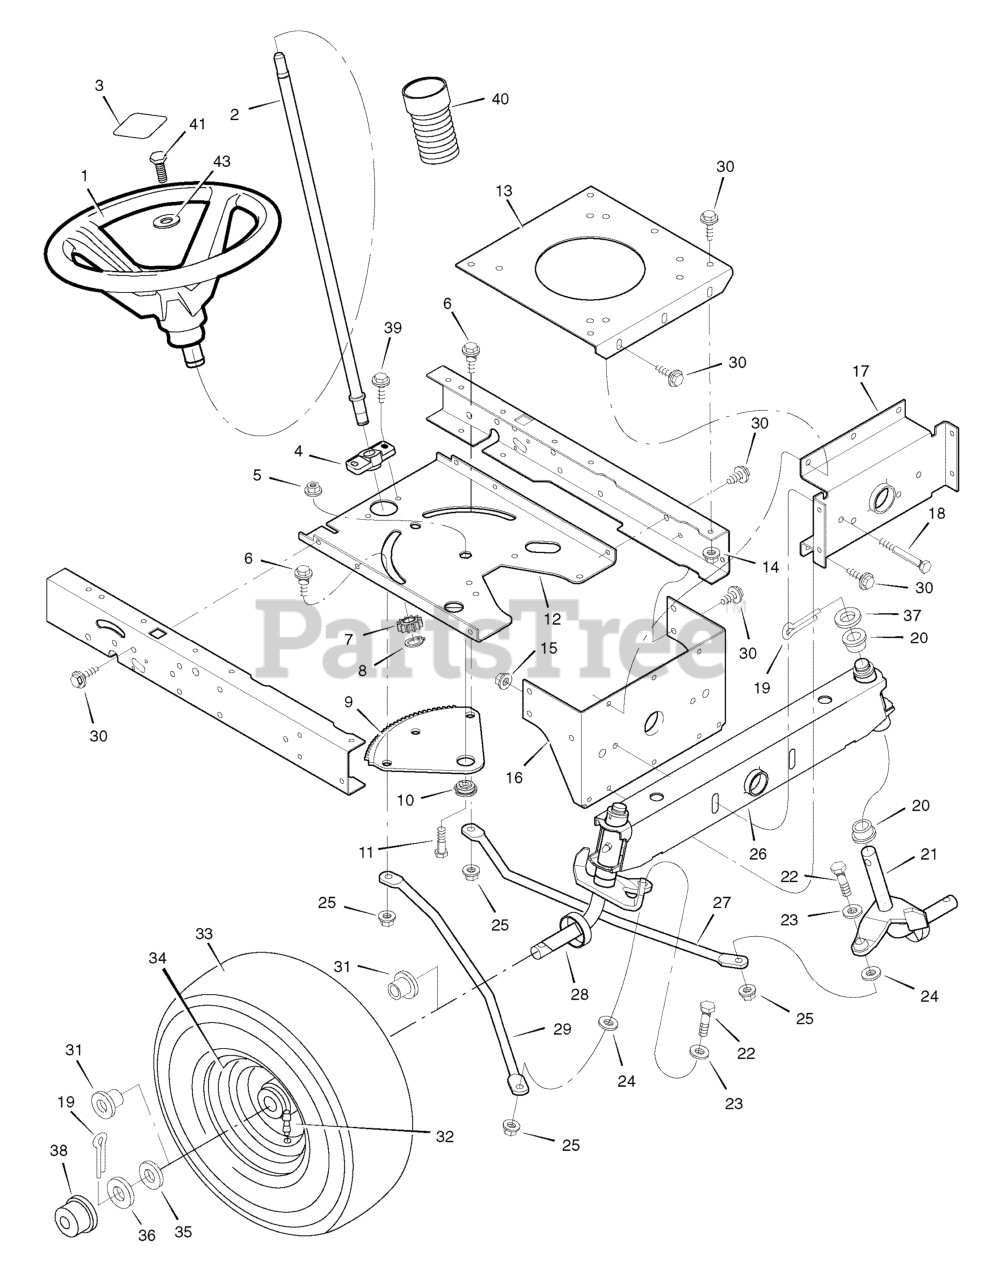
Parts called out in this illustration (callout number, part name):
1	Wheel, Steering
2	Post, Steering
3	Cover, Steering Wheel
4	Bearing
5	Nut, Flange
6	Bolt, Shoulder
7	Gear, Pinion
8	Ring, Snap
9	Gear, Sector
10	Bearing
11	CAPSCREW, Hex Head, 5/16-18 x 1
12	Plate, Steering
13	Plate, Engine
14	Nut, Flange
15	Nut, Flange
16	Bracket, Hanger
17	Axle, Hanger
19	Pin, Cotter
20	Bearing
21	Spindle Assembly, Left
22	Bolt
23	Washer
24	Washer
25	Nut, Flange
26	Axle Assembly
27	Drag Link, Left
28	Spindle Assembly, Right
29	Drag Link, Right
31	Bearing
32	Stem, Valve
34	Wheel and Tire Assembly
38	Hub Cap
40	Bellows
41	Screw, Hex
43	Washer
